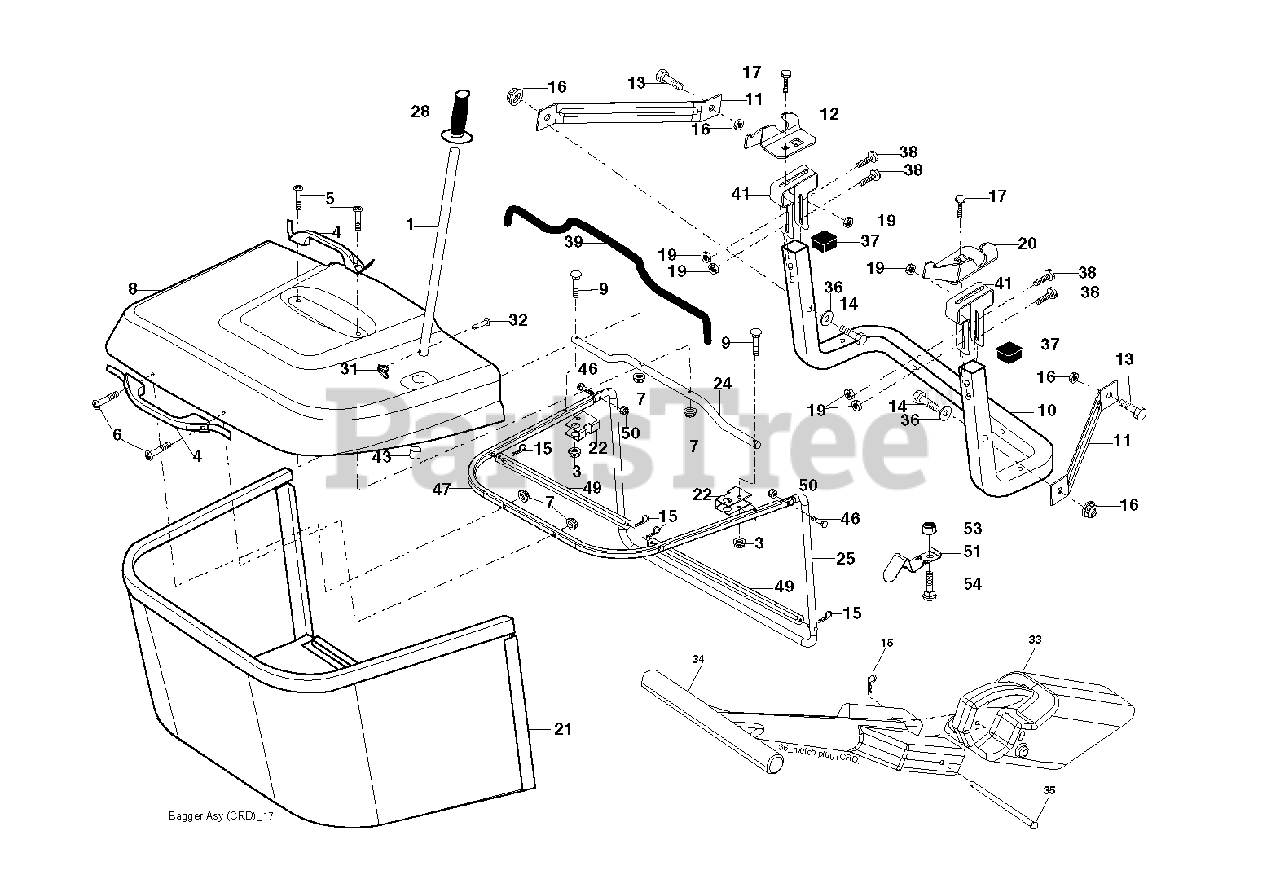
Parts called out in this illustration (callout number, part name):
1	TUBE HANDLE
3	NUT T
5	SCREW.PAN.HEAD
11	BRACKET
14	BOLT-HEX EAK
15	RETAINER-SPRNG RB
16	NUT LOCK FLG 3/8-16 UNC
17	BOLT
19	NUT LOCK HEX FLANGE 5/16-18
20	BRKT.PIVOT.RH.CRD
21	BAGGER.ASM.CRD.2007
22	BRACKET
24	TUBE
28	GRIP.HANDLE.BLACK
31	RETAINER CLIP
32	RIVET,DRILLED
33	PLUG
35	PIN
38	BOLT.5/16-18X2.5
39	SEAL.BAGGER.CRD
41	BRKT, BAGGER
43	PLUG, TUBING END
46	BOLT.CARRIAGE.5/16-18
50	NUT.71038.31-18.HEX.NYLOCK
53	NUT
54	BOLT
